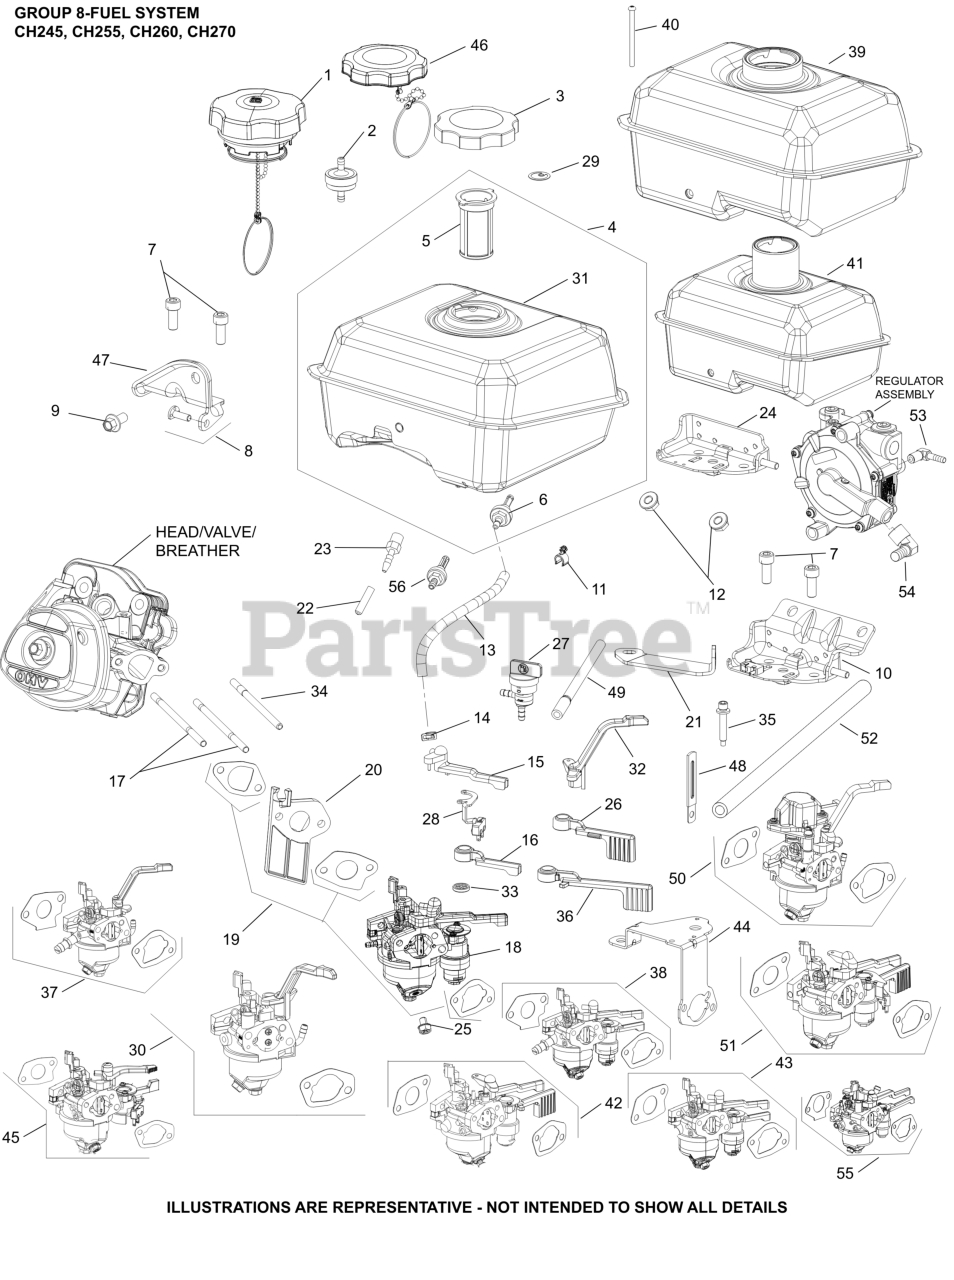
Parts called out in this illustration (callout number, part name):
1	CAP, FUEL ASSEMBLY
5	FILTER, FUEL TANK
7	SCREW, HEX SOCKET HD CAP
8	BRACKET ASSY, FUEL TANK
9	SCREW, FLG 8X1.25X16
11	CLIP, FUEL HOSE
13	LINE, FUEL (10"-CUT TO LENGTH)
14	CLAMP, FUEL LINE
15	LEVER, CHOKE
17	STUD, CARBURETOR
19	KIT, INTAKE GASKET
20	KIT, CARBURETOR INSULATOR
31	KIT, FUEL TANK
36	KIT, FUEL SHUTOFF LEVER
42	KIT, CARBURETOR COMPLETE
56	FITTING, FUEL ASSY
NI	KIT, HIGH ALT (4000-8000 FT)
NI	KIT, HIGH ALT (8,000+ FT)
NI	KIT, CARBURETOR REPAIR (RUIXING)
